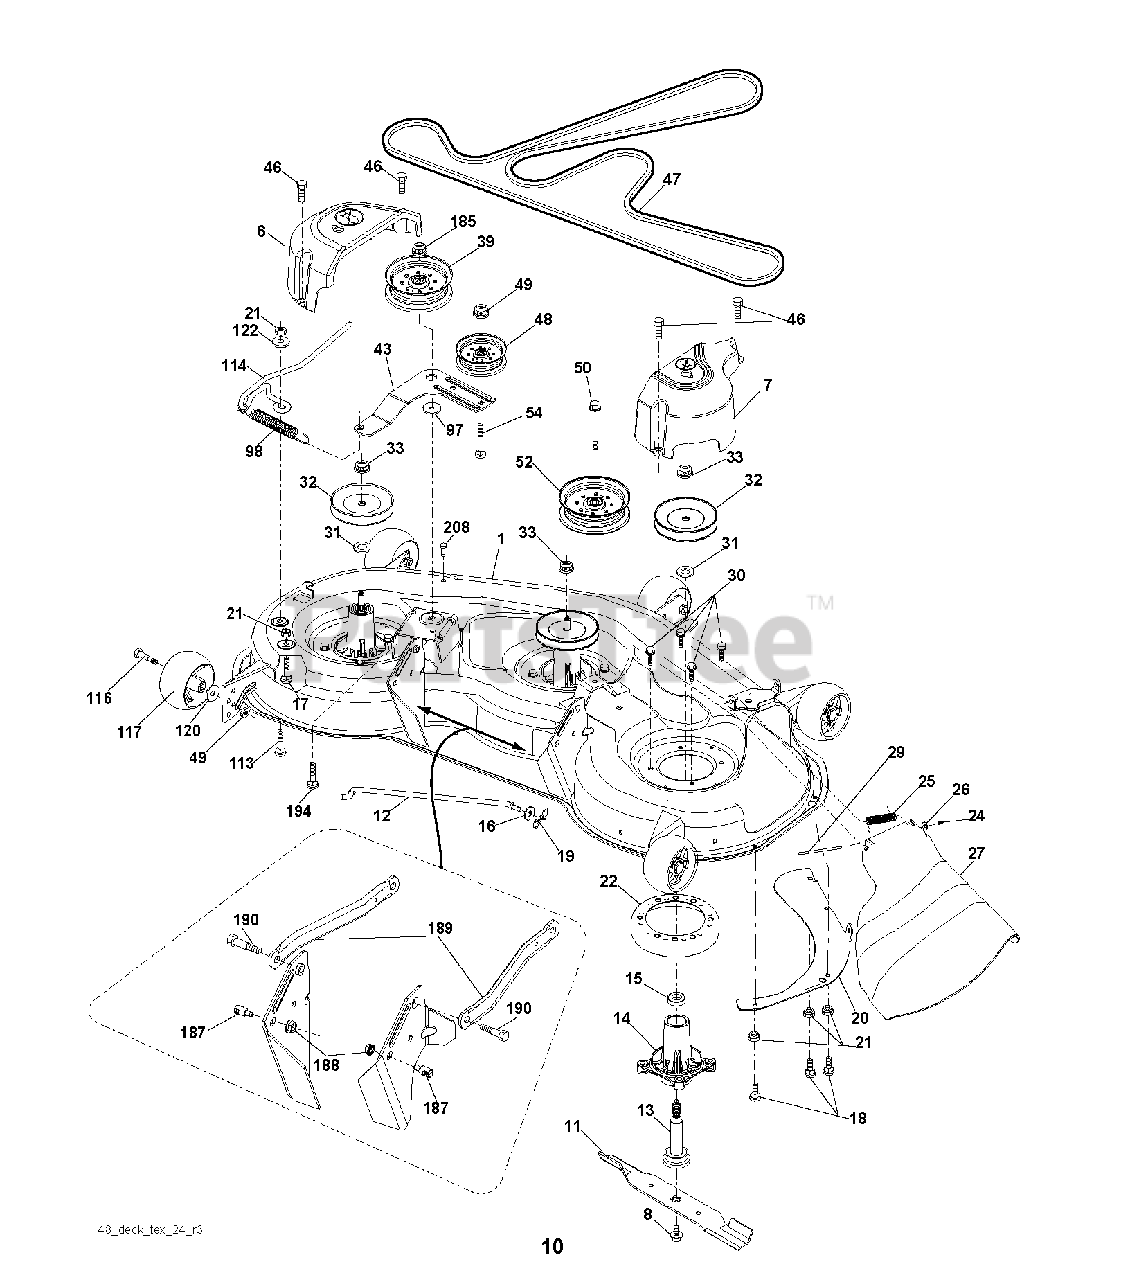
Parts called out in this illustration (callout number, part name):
1	DECK.WELDMENT.48"2006
6	COVER.MANDREL.LH.48"
7	COVER.MANDREL.RH.48"
8	BOLT 7/16 ASM BLADE
11	48" HI-LIFT BLADE
12	ROD.ANTI.SWAY.48/54"TE
13	SHAFT ASM MANDREL
14	HOUSING MANDREL
16	WASHER
17	BOLT
18	BOLT
19	PIN.COTTER.5/16.BOW TI
20	BAFFLE, VORTEX MWR
21	LOCKNUT
22	STRIPPER, MWR ROUND
24	CAP-SLEEVE LT
25	SPRING, TORSION
26	NUT PUSH M
27	DEFLECTOR SUBS TO 532 180655
29	ROD.HINGE
30	SCREW, WASHER HEAD
31	WASHER.SPACER.MANDREL
32	PULLEY MANDREL
33	NUT.FLANGE.LOCK.TOP
39	PULLEY.IDLER.4.50/HUB SPECIAL
43	ARM.IDLER
46	SCREW.1/4-20X5/8
47	BELT.DRIVE.DECK
48	PULLEY.IDLER.48"PRIMARY
49	NUT LOCK FLG 3/8-16 UNC
50	SCREW TT 3/8-16X2-1/4 UNC
52	PULLEY.IDLER.2006
54	BOLT.3/8-16X1.50
98	SPRING, DECK DRIVE
114	ROD.TENSION.RELIEF.TEX
116	BOLT.SHOULDER.3/8-16X3-5/8
117	WHEEL. GUAGE RALLY
122	BUSHING.RELIEF.TENSION
185	NUT.LOCK.FLANGE.7/16
187	STUD.FASTNER.W/ANTI-ROTATE
188	NUT LOCK HEX FLANGE 5/16-18
189	ARM.SUSPENSION.MOWER
190	BOLT.SHOULDER
194	BOLT.CARR.SQNK.7/16
208	SCREW 3/8-16X1/2
